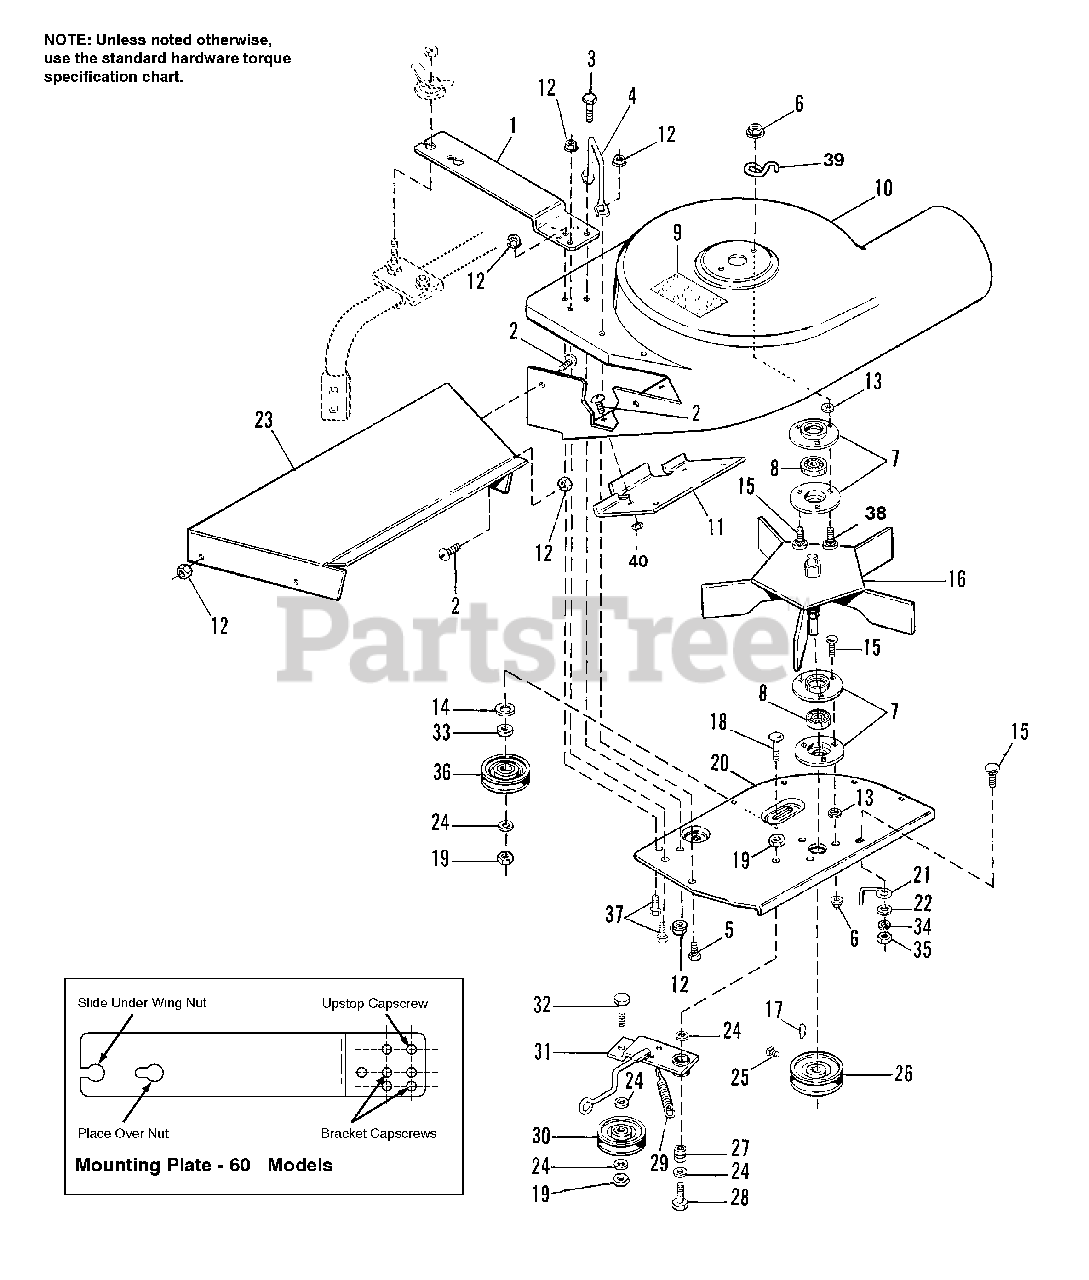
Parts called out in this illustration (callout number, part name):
1	PLATE, Mounting
2	CAPSCREW, Hex Hd,1/4-20 x 5/8
3	CAPSCREW, Hex Hd,1/4-20 x 2-1/4
4	STOP, Deflector
5	CAPSCREW, Hex Hd, 1/4-20 x 7/8
6	NUT, Hex Flange Whiz Lock, 5/16-18
7	RETAINER, Bearing
9	DECAL, Danger
10	HOUSING, Blower
11	HOOK, Stone Guard
12	NUT, Hex Flange Whiz Lock, 1/4-20
13	NUT, Push, 5/16
14	WASHER, Plain,1/2
15	CARRIAGE BOLT, 5/16-18 x 3/4
16	FAN ASSEMBLY (5 Blade)
17	KEY, Woodruff, 3/16
18	CARRIAGE BOLT, 3/8-16 x 1-1/4
19	NUT, Hex Jam Lock, 3/8-16
20	PLATE, Shroud
22	WASHER, 5/16
24	WASHER, 3/8
25	SETSCREW, Sqr Hd, 5/16-18 x 3/8
26	PULLEY, Driven
27	SPACER
28	CAPSCREW, Hex Hd, 3/8-16 x 1-1/2
29	SPRING, Extension
30	PULLEY, Idler, Adjustable
31	IDLER ARM ASSEMBLY
32	CAPSCREW, Hex Hd, 3/8-16 x 1
33	WASHER, 3/8
34	WASHER, Lock, 5/16
35	NUT, Hex, 5/16-18
36	PULLEY, Idler, Fixed
37	CAPSCREW, Hex Hd, 1/4-20 x 3/4
38	CARRIAGE BOLT, 5/16-18 x 7/8
40	NUT, Hex Nylon Lock, 1/4-20
